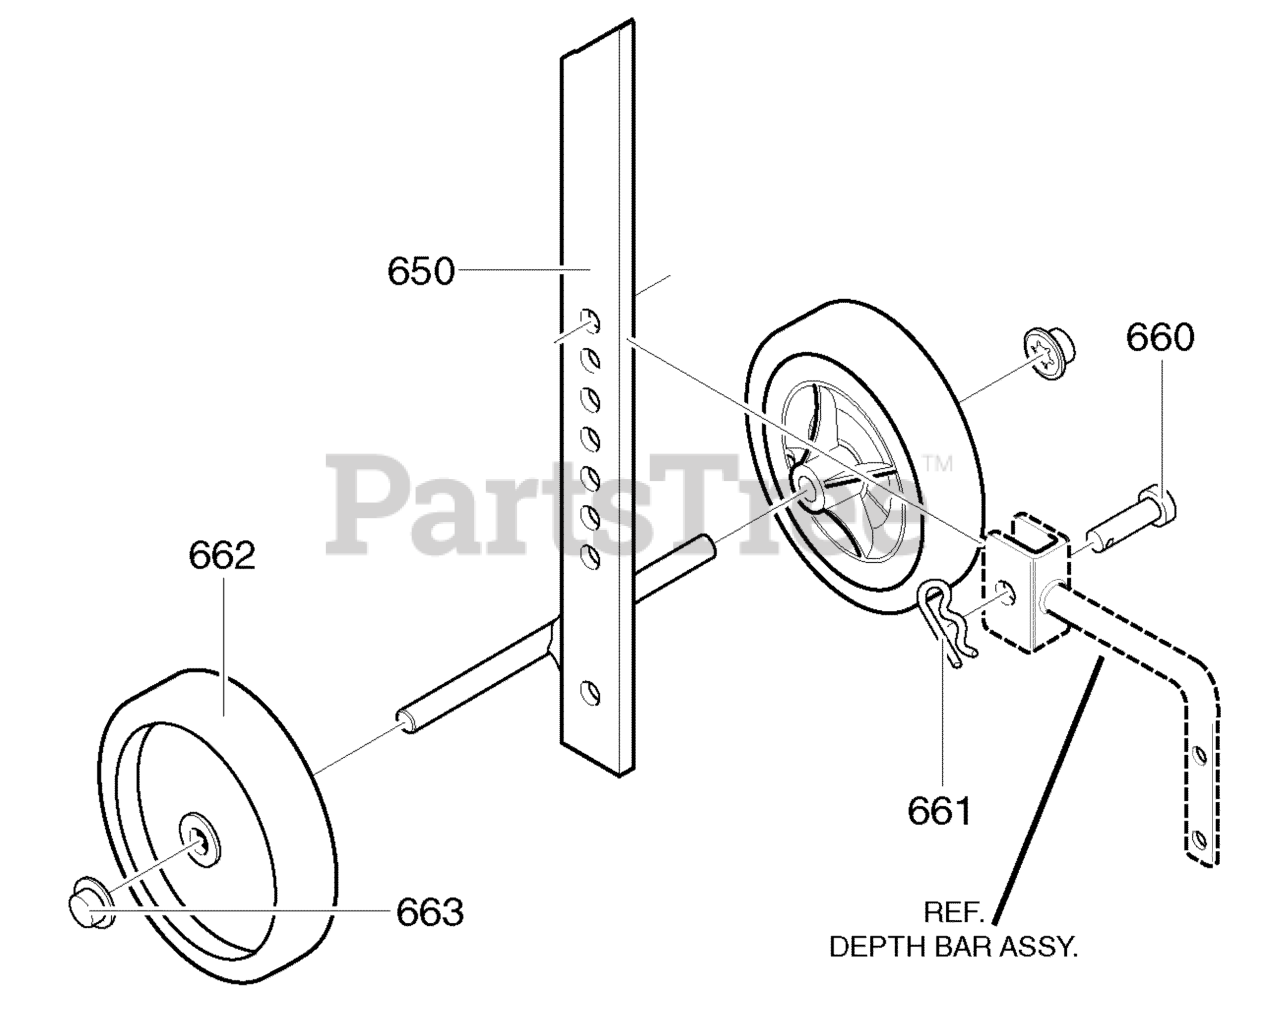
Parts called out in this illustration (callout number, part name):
650	WHEEL SUPPORT ASSEMBLY
660	PIN, Clevis
662	TIRE & RIM
663	NUT, Push on
